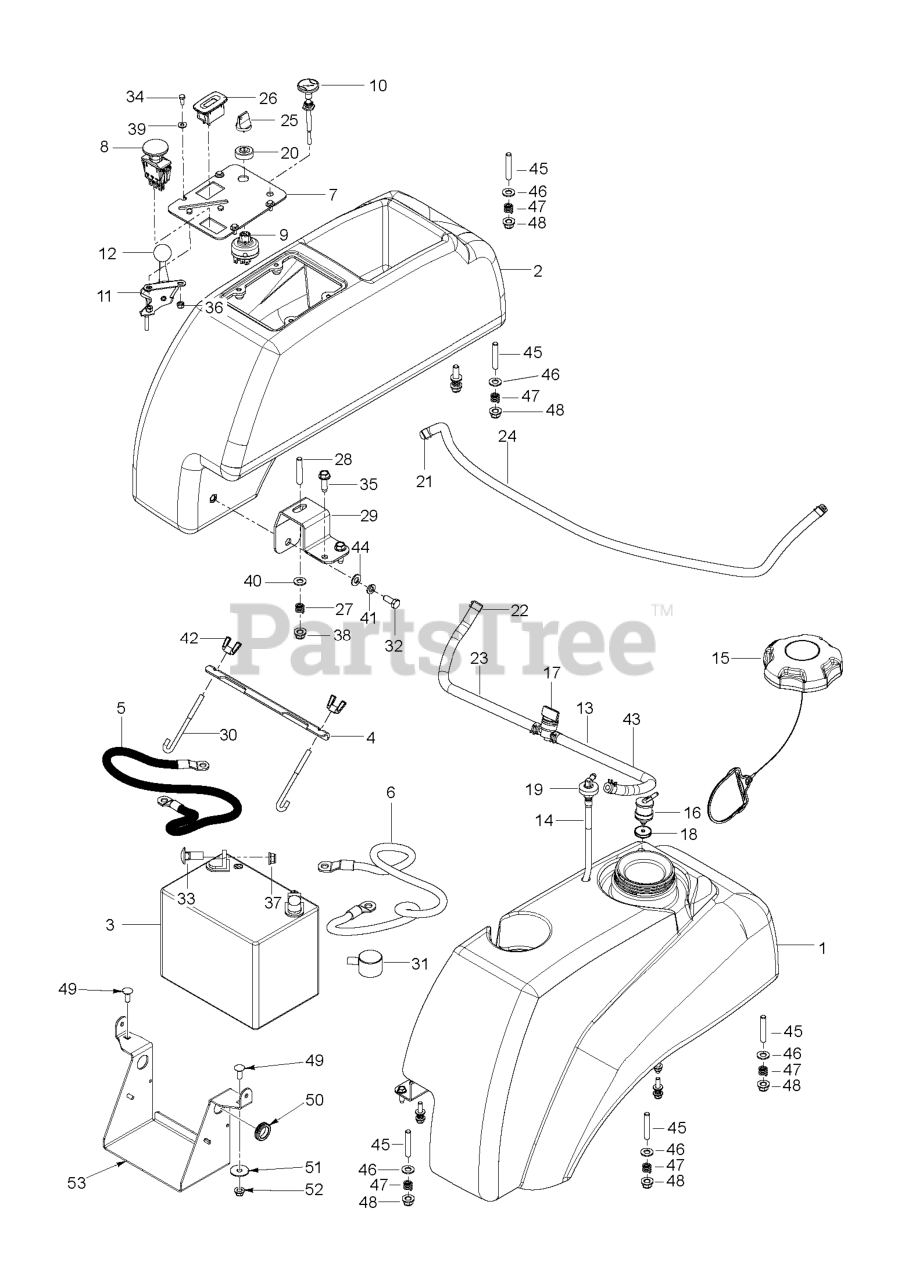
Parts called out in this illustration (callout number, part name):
2	FENDER CONSOLE
3	BATTERY, 12 V 330 AMP
3	BATTERY WET NOT SELLABLE
4	BRACKET.BATTERY.MOUNT.PLATED
4	Brackets
5	CABLE.GROUND.BATT.MZ.BLACK.39"
6	CABLE.BATT.SOLENOID.MZ.RED.25"
7	PLATE.CONSOLE.BLACK
8	RP SWITCH.PTO.TERMINAL.STD.RED
9	SWITCH, IGNITION, INDAK
10	CHOKE CABLE
10	CHOKE CONTROL CABLE 57"
10	CABLE, CHOKE
11	THROTTLE CABLE
11	THROTTLE CONTROL W/BALL KNOB
12	KNOB.ROUND.BALL.BLACK
13	FUEL.HOSE.SHUT.OFF.ASM.10".10"
13	FUEL.HOSE.SHUT.OFF.ASM.10".26"
14	FITTING, FUEL
15	CAP, FUEL
16	VALVE.FUEL.CHECK
17	FUEL VALVE
18	GROMMET, CHECK VALVE
19	RUBBER GROMMET
20	CAP IGNITION NUT
21	CLAMP, HOSE
22	HOSE CLAMP
23	HOSE.1/4".LOW.PERM.FUEL.LN.10"
24	HOSE.3/16".VAPOR.LINE.39"LGTH
24	HOSE.3/16".VAPOR.LINE.27"LGTH
24	HOSE.3/16".VAPOR.LINE.55"LGTH
25	KEY, IGNITION
26	GUAGE.SRVCMNDR.HRMTR.
28	STUD, 5/16C
29	SUPPORT.PNT.TANK.FRONT.STAMPED
31	COVER.TERMINAL.BATTERY
32	HCS 5/16C X 3/4
33	GSPW Bolts
33	BOLT 5/16C X 3/4" CARRIAGE
34	SWITCH, IGNITION, INDAK
34	HCS #10-24 X 1/2
35	SCREW
36	NUT 10-24 NYLOC
37	WING NUT 1/4
37	NUT HEXAGON FLANGE 5/16-18 ST
37	5/16-18 NYLOC FLANGE NUT
38	5/16-18 NYLOC FLANGE NUT
40	WASHER
41	WASHER.LOCK.HVY.HLCL.SPR.5/16
42	WING NUT 1/4
43	HOSE.1/4".LOW.PERM.FUEL.LN.26"
44	WASHER
45	STUD, 5/16C
46	WASHER
47	SPRING
48	5/16-18 NYLOC FLANGE NUT
49	Bolts
50	RUBBER GROMMET
51	Washers
52	GSPW Nuts
53	BRACKET BATTERY BLACK MS-431
